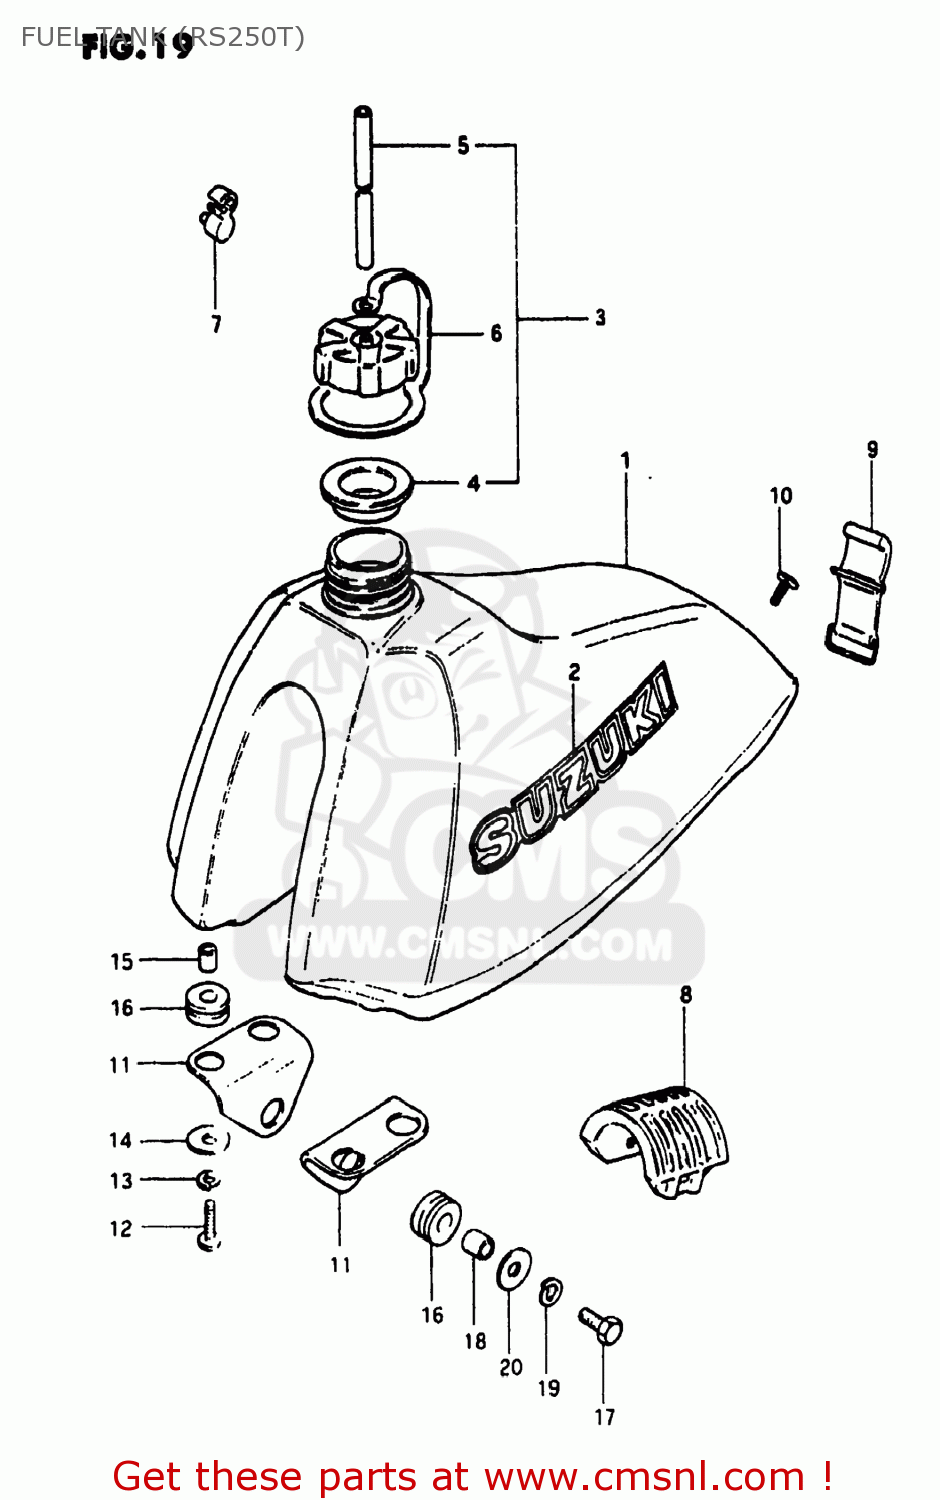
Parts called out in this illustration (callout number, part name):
1	TANK ASSEMBLY,FUEL
2	EMBLEM
3	CAP SET,FUEL TANK
4	GASKET,FUEL TANK CAP (NAS)
5	HOSE
6	BAND,FUEL TANK CAP
7	CLAMP,BREATHER HOSE
8	CUSHION,FUEL TANK
9	BAND
10	SCREW(6X18)
11	BRACKET,FUEL TANK,LOWER
12	SCREW
13	LOCK WASHER
14	WASHER (6.5X24X1.6)
15	SPACER(6.8X12X11)
16	CUSHION
17	BOLT (8X30)
18	SPACER (8.8X12X11)
19	LOCK WASHER
20	WASHER (8.2X24X1.6)
